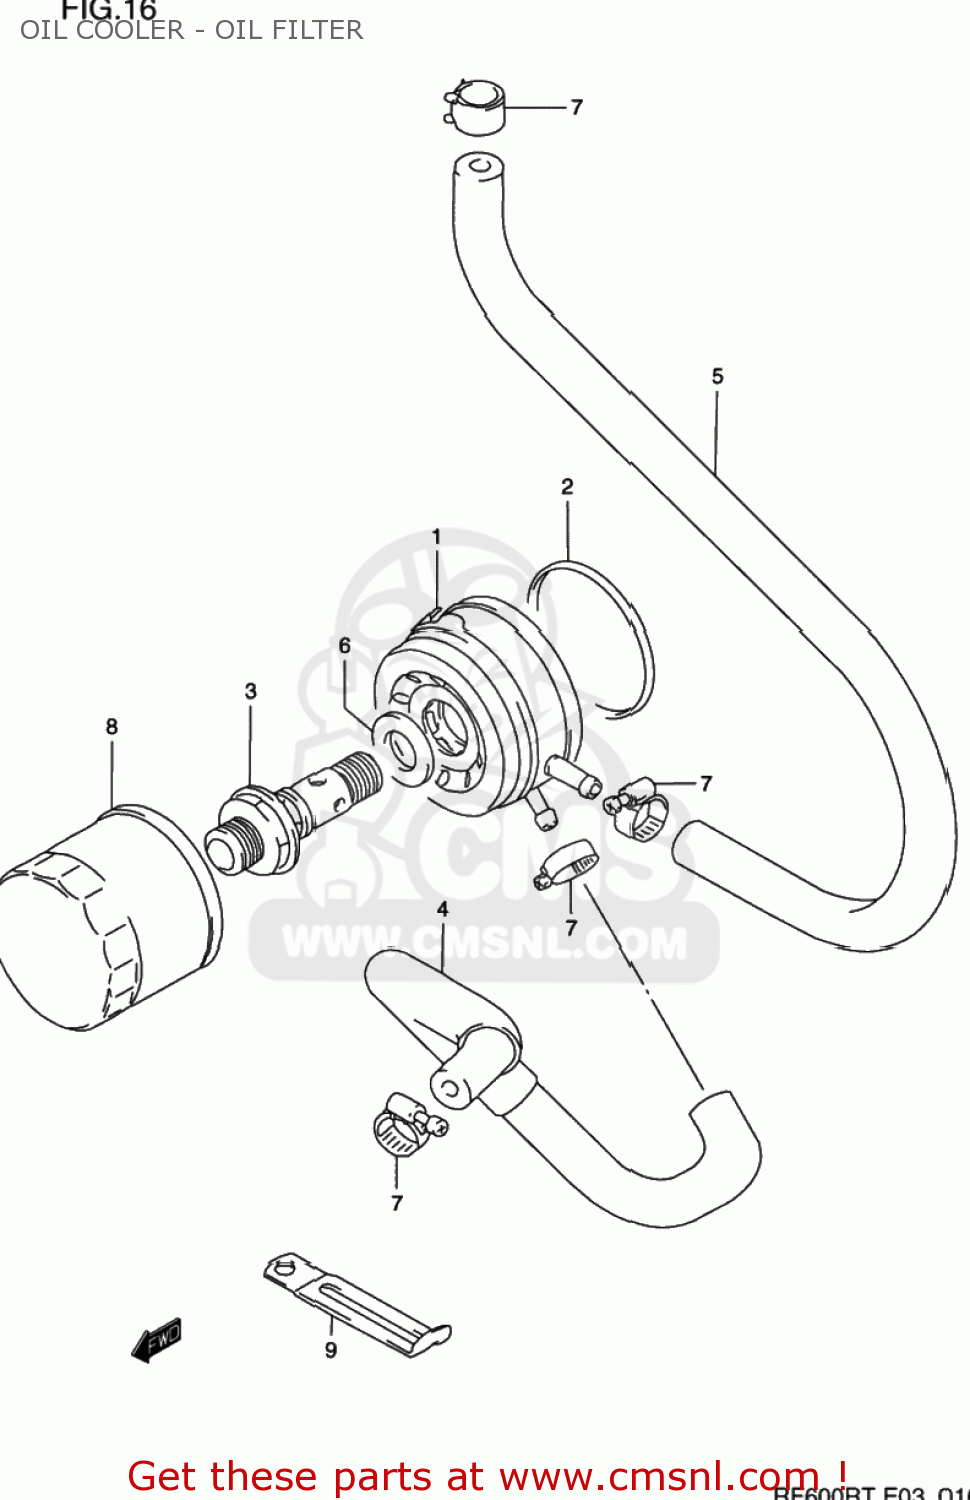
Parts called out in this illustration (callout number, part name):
1	COOLER ASSY,OIL
2	O RING(D:3.1,ID:63.9)
3	BOLT,OIL COOLER UNION
4	HOSE,OIL COOLER WATER IN
5	HOSE,OIL
6	SHIM
7	CLIP
8	FILTER ASSEMBLY,ENGINE OIL
9	CLAMP
